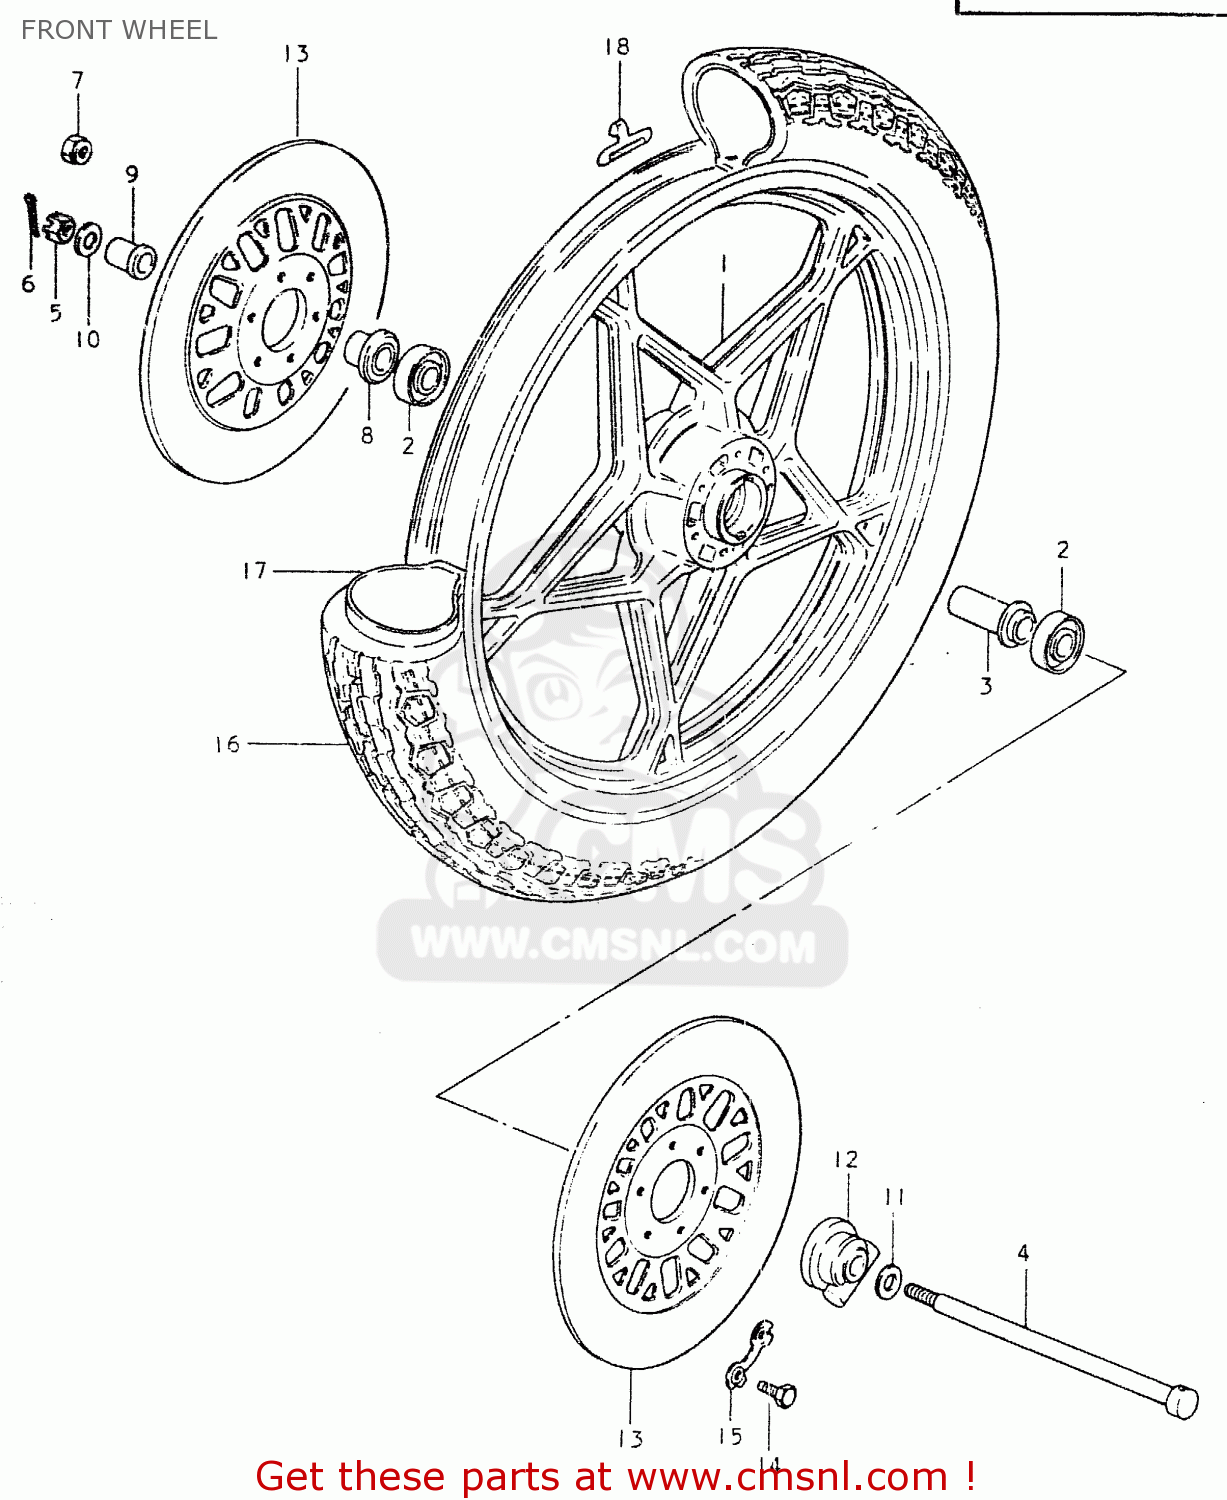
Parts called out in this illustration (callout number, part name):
1	WHEEL, FRONT
2	BEARING
3	SPACER,FR HUB BEARING
4	AXLE,FR
5	NUT 12MM
6	COTTER PIN
7	NUT
8	SPACER,FR AXLE,R
9	SPACER
10	WASHER
11	WASHER(15.5X26X2.3)
12	BOX ASSY,SPEEDOMETER GEAR
13	DISC,FR BRAKE
14	BOLT(8X25)
15	WASHER
16	TIRE,FRONT
17	TUBE,INNER
18	BALANCER,WHEEL
